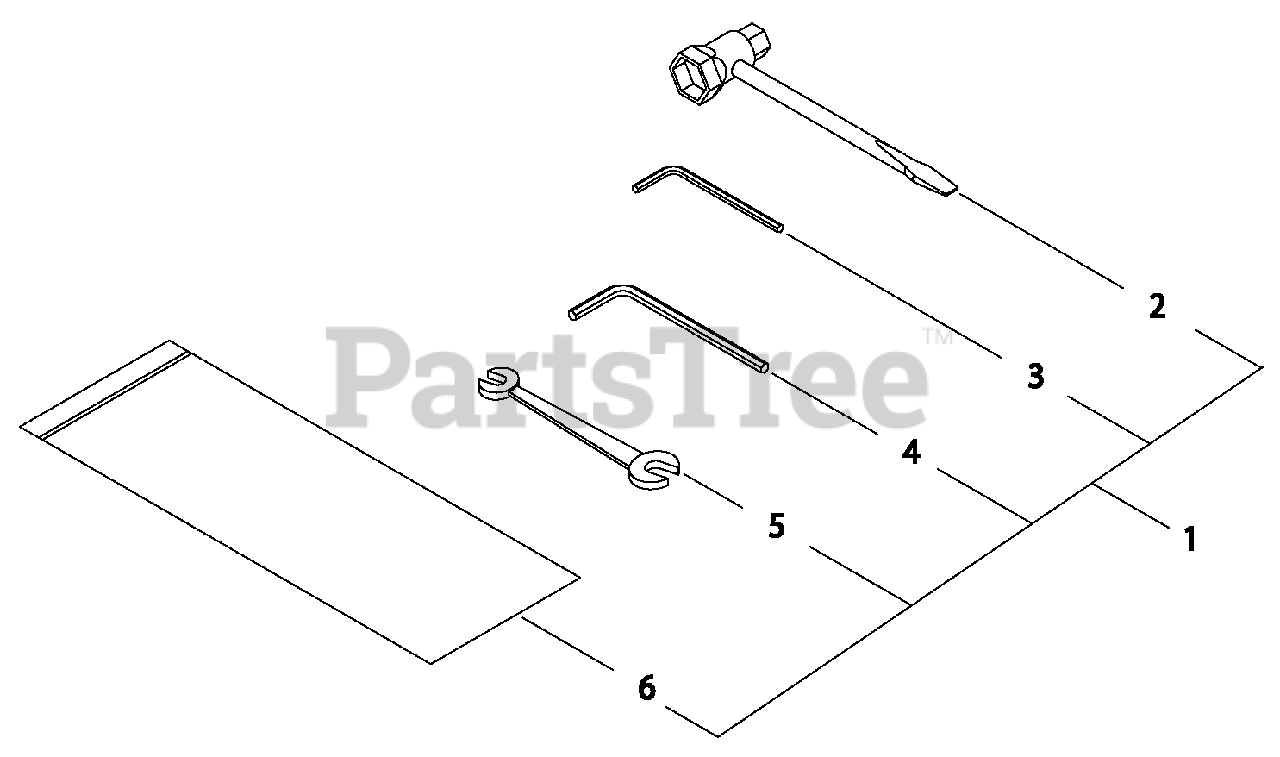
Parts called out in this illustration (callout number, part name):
1	TOOL KIT, SERVICE
2	T-WRENCH 17×19 MM
3	WRENCH, ALLEN 4 MM
4	WRENCH, ALLEN 5 MM
5	SPANNER 8×10
6	BAG, TOOL
